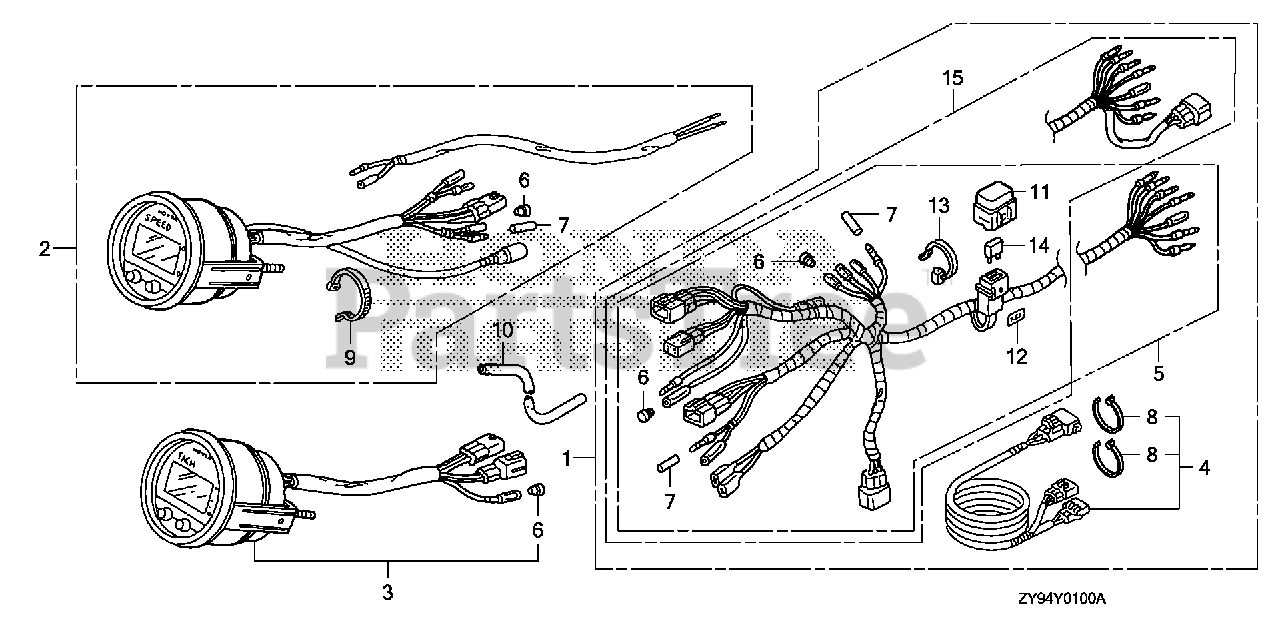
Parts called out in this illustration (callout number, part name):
1	HARNESS KIT, METER (DIGITAL) (INCLUDE 32540-ZY3-801)
1	HARNESS KIT, METER (DIGITAL) (INCLUDE 32540-ZY3-802) (FOR 2-LED)
2	SPEEDOMETER KIT (DIGITAL) (FOR 32540-ZY3-800/801)
2	SPEEDOMETER KIT (DIGITAL)(USA)
3	METER KIT, TACHO (DIGITAL) (USA)(USE FOR 32540-ZY3-801) (NOT AVAILABLE)
3	METER KIT, TACHO (DIGITAL)(USA) (NOT AVAILABLE)
4	WIRE ASSY., INDICATOR (DIGITAL) (FOR 2-LED)
5	HARNESS ASSY., METER (A)(DIGITAL)
6	PLUG, CONNECTOR (INNER)
7	PLUG, CONNECTOR (OUTER)
8	TIE, CABLE (2.4X92) (NATURAL) (FOR 2-LED)
9	BAND (BLACK 3.5X140)
10	TUBE, SPEED METER (4X7X8000)
11	COVER ASSY., FUSE (7.5A)
12	MARK, FUSE (7.5A)
13	TIE, CABLE
14	FUSE, BLADE (7.5A)
15	HARNESS ASSY., METER (A)(DIGITAL) (FOR 2-LED)
15	HARNESS ASSY., METER (A)(DIGITAL) (FOR 4-LED)
